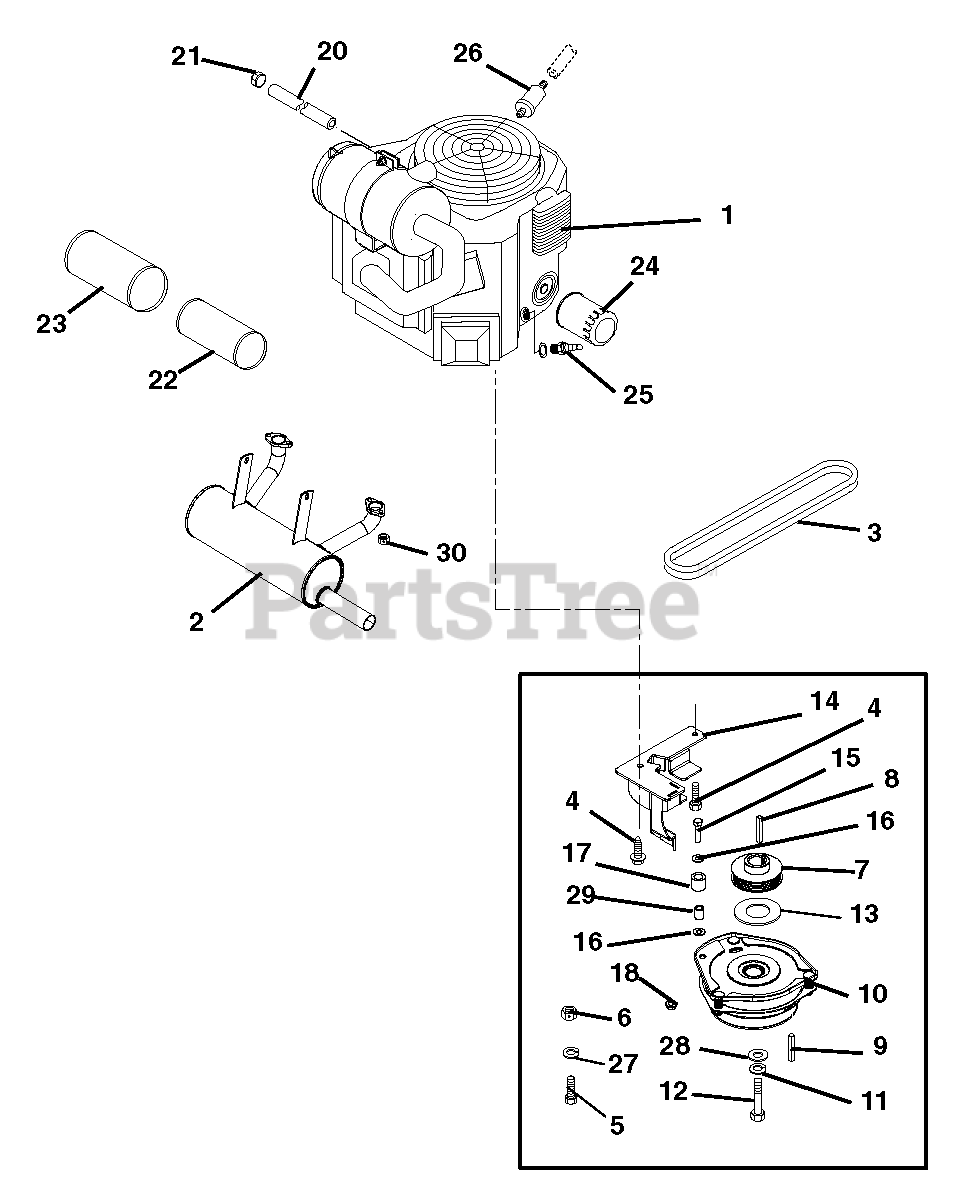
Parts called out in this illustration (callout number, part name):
1	Engine, Generac GTV990 (LPG) (992182)
2	Muffler, Generac GTV990 (LPG) (992182)
3	Belt, Poly-V
4	Screw, Tapping Hex Washer Head .38-16 x 1.
5	Bolt, Hex .31-18 x 1.75 Grade 5
6	Nut, Locking Top Flange .31-18
7	Sheave, Poly V 1.27 x 3.275
8	Key-Square .25 x 1.25 x .25 SAE
9	Key-Straight .25 x 1.75 x .25
10	Clutch, Electric
11	Washer, Locking .44 x .109
12	Bolt, Hex .44-20 x 2.25 Grade 5
13	Washer, 1.13ID x 1.75OD x .048 Steel
14	Anchor Clutch
15	Bolt-Hex .38-16 x 1.50 Grade 5
16	Washer-Flat-Steel .406 x .812 x .065
17	Bumper, Rubber .62 x 1.0 x .88 LG
18	Nut-Locking-Top-Flange .38-16
19	Cable Tie LG 5-1/2
20	Hose, Hydraulic .38-11-0K M6N0-M6N0
21	Pipe Cap .38 NPT Female
22	Element, Inner Safety
23	Element, Outer Primary
24	Oil Filter
25	Spark Plug
26	Fuel Filter
27	Washer, Locking-EXT.326 x .599 x .031
28	Washer, Flat Steel .469 x 2 x .25
29	Bushing, .407 x .625 x .813
30	Nut, Locking, Top M8-1.25
